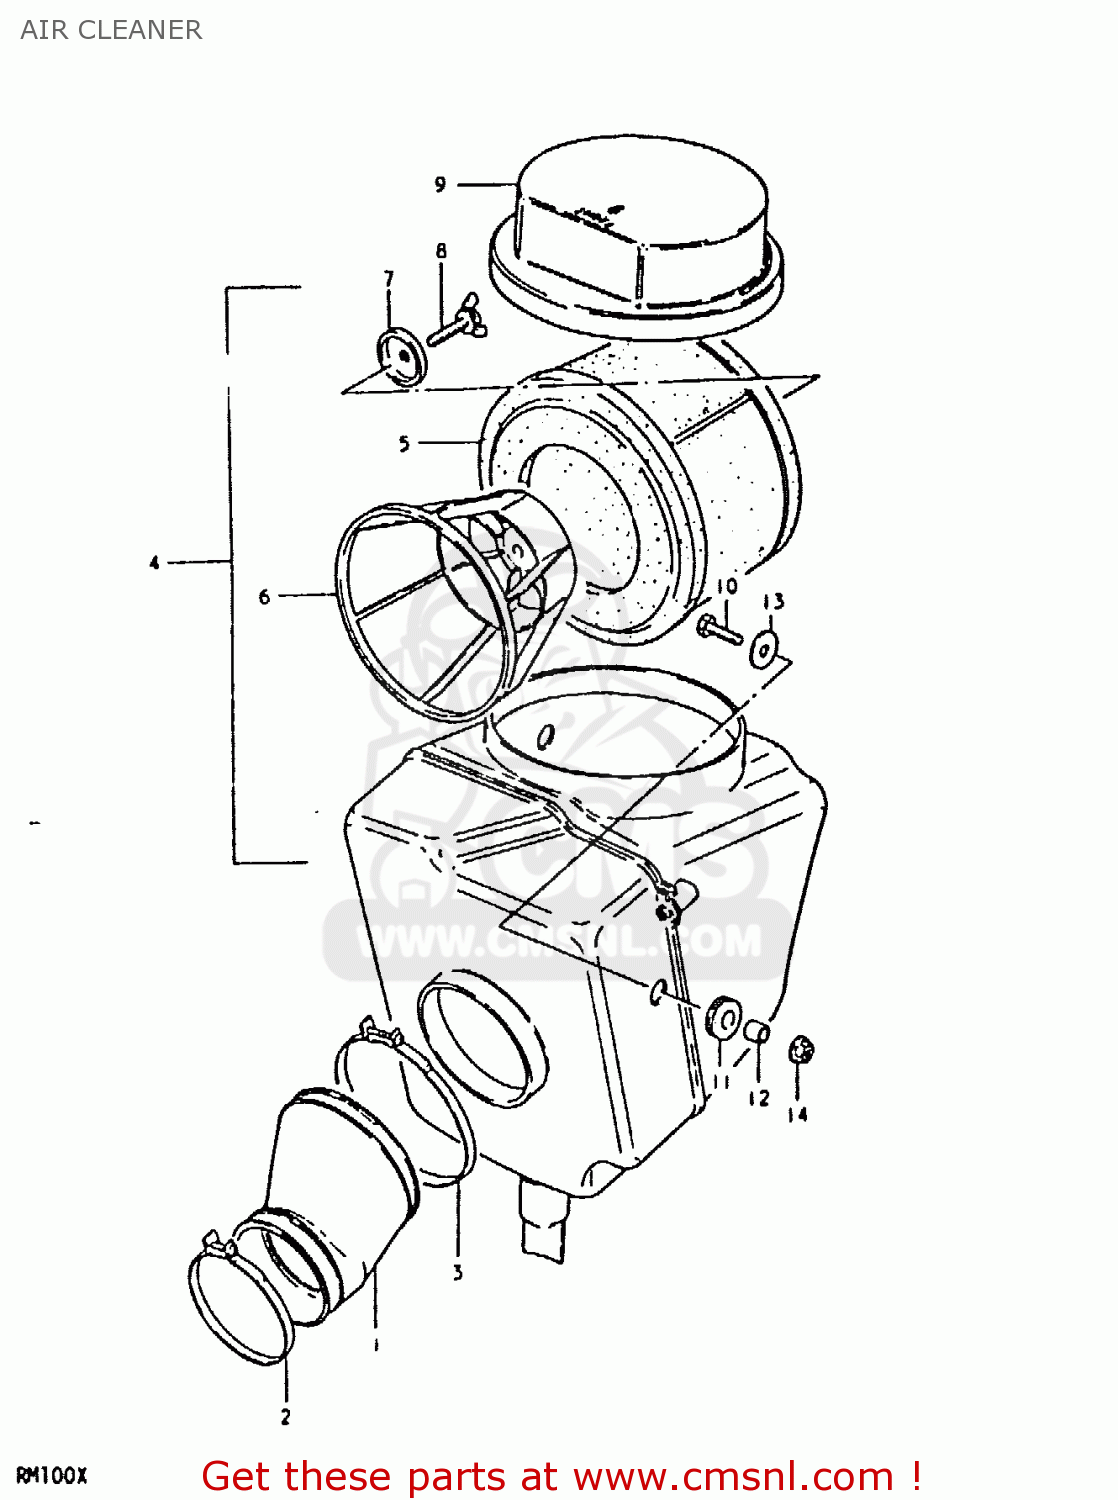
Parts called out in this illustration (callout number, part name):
1	TUBE,AIR CLEANER OUTLET
2	CLAMP
3	CLAMP
4	CLEANER ASSEMBLY,AIR
5	FILTER
6	HOLDER
7	HOLDER,FILTER
8	WING BOLT,AIR CLEANER
9	CAP,AIR CLEANER
10	BOLT
11	CUSHION
12	SPACER (6.1X9X9)
13	WASHER (6.5X20X1.2)
14	NUT
